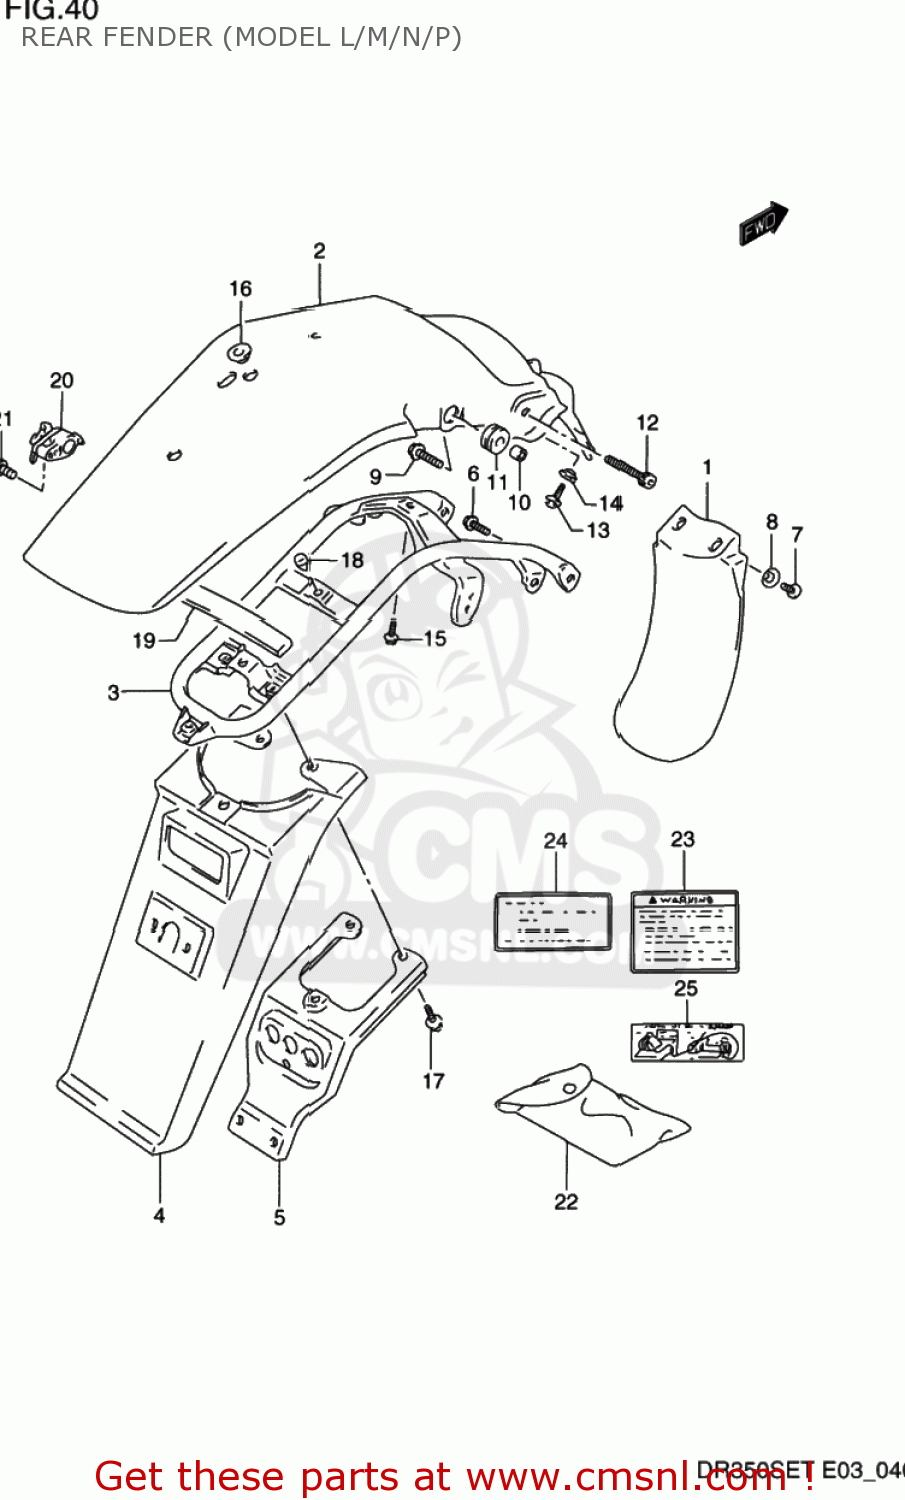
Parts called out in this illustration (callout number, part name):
1	BODY,RR FENDER FR
2	FENDER,REAR
3	REINF,RR FENDER
4	EXTENSION,RR FENDER
5	REINFORCMENT,REAR FENDER
6	BOLT
7	SCREW 6X12
8	WASHER
9	BOLT(8X30)
10	SPACER (8.8X12X7)
11	CUSHION
12	BOLT(8X30)
13	BOLT
14	WASHER
15	BOLT
16	WASHER(14.2X26X1.2)
17	BOLT
18	CUSHION
19	CUSHION,REAR FENDER
20	LOCK SET,HELMET
21	SCREW
22	TOOL SET
23	LABEL
24	LABEL,STARTING CAUTION
25	LABEL,PIPING DIAG
26	LABEL (TIRE AIR PRESSURE)
27	MANUAL, OWNER'S
